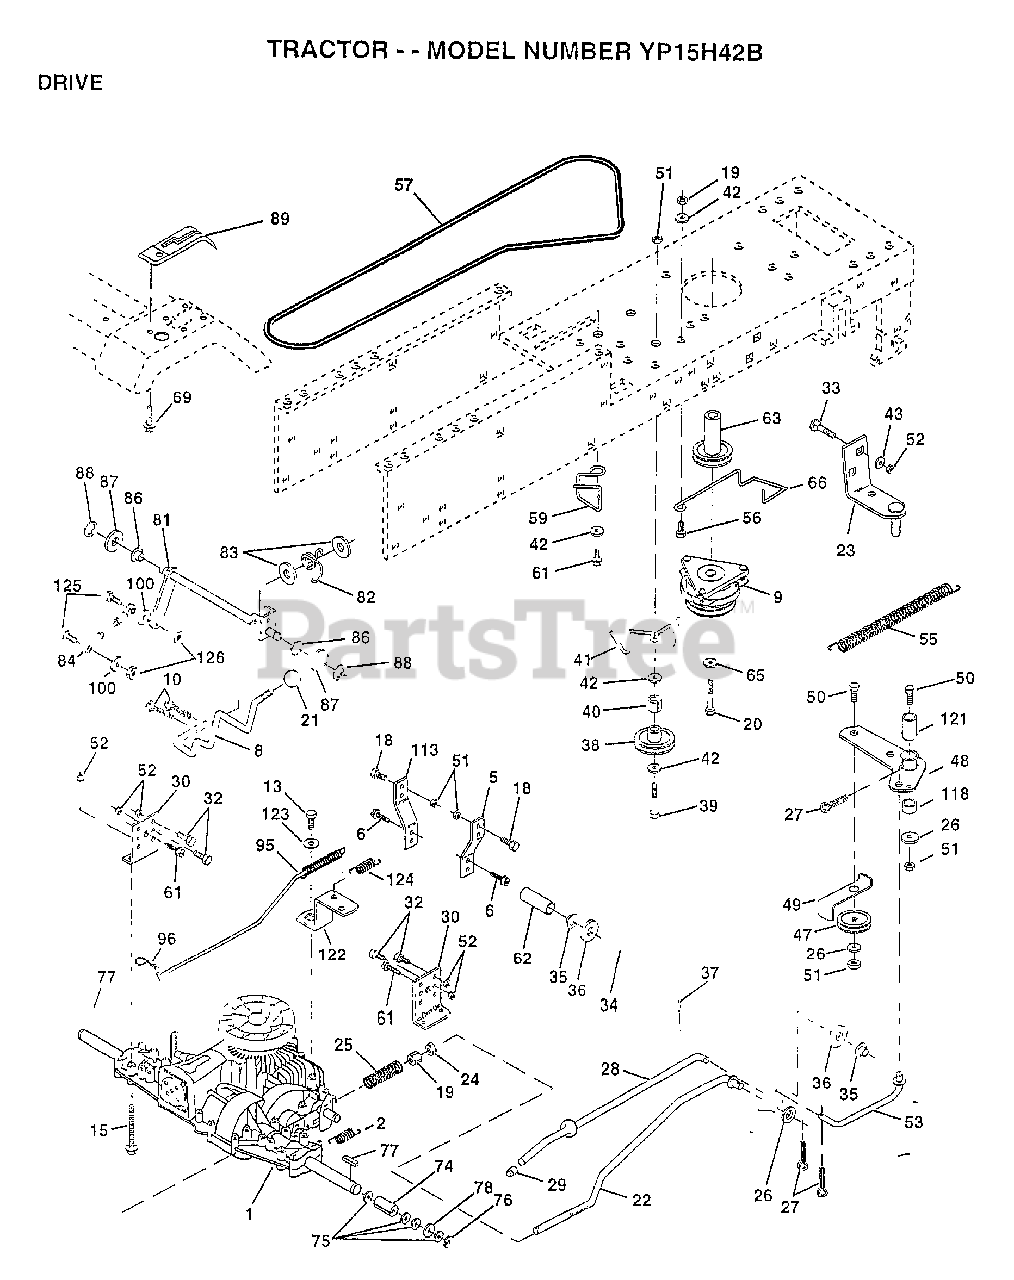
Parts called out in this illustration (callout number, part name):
1	TRANSAXLE, PEERLESS
2	SPRING.BRAKE.RETU
5	STRAP TORQUE
6	SCREW
8	ROD SHIFT FEND LT
9	CLUTCH.ELECT.EVX.
10	PIN COTTER 1/8
13	BOLT.1/4-28.W/PAT
15	BOLT.HX.FLG.5/16
18	BOLT
19	NUT
20	BOLT.7/16-20X4.25
21	KNOB DLX BLK/BLK
22	BRAKE ROD
23	BRACKET.CLUT.MTG.
24	NUT
25	SPRING ROD LT
26	WASHER
27	COTTER PIN
28	ROD.BRAKE.PARK.LT
29	PLUNGER CAP T
30	TRANSAXLE MTG BKT
32	BOLT
33	BOLT
34	SHAFT ASM-PEDAL F
35	NYLON BEARING
36	WASHER LT
38	PULLEY.IDLER.FLAT
39	BOLT
40	SPACER T
42	WASHER
43	WASHER T
48	BELLCRANK ASM
49	RETAIN BELT
53	"LINK, CLUTCH T"
55	"SPRING, RETURN LT"
57	"V-BELT,GRD DRIVE"
59	KEEPER BELT CNTSP
61	SCREW
62	"COVER,PEDAL"
63	PULLEY.CLUTCH.EVX
65	LOCKWASHER
66	KEEPER-BELT
69	SCREW HEXWSH H-L
74	"SPACER AXLE,PVST"
75	WASHER
76	E-RING LT
77	SQUARE KEY
78	WASHER
81	SHAFT ASM CROSS
82	"SPRING,TORSION"
83	WASHER
84	"ROD TIE, PVST 20"""
86	BUSHING
87	WASHER D
88	KLIP RING
95	ROAD ASM BYPASS
96	RETAINER M
100	WASHER M
113	"STRAP,TORQUE"
118	SPACER-BELLCRANK
121	NYLINER-CLUTCHING
122	"PLATE-BYPASS,PVST"
124	SPRING RETURN
